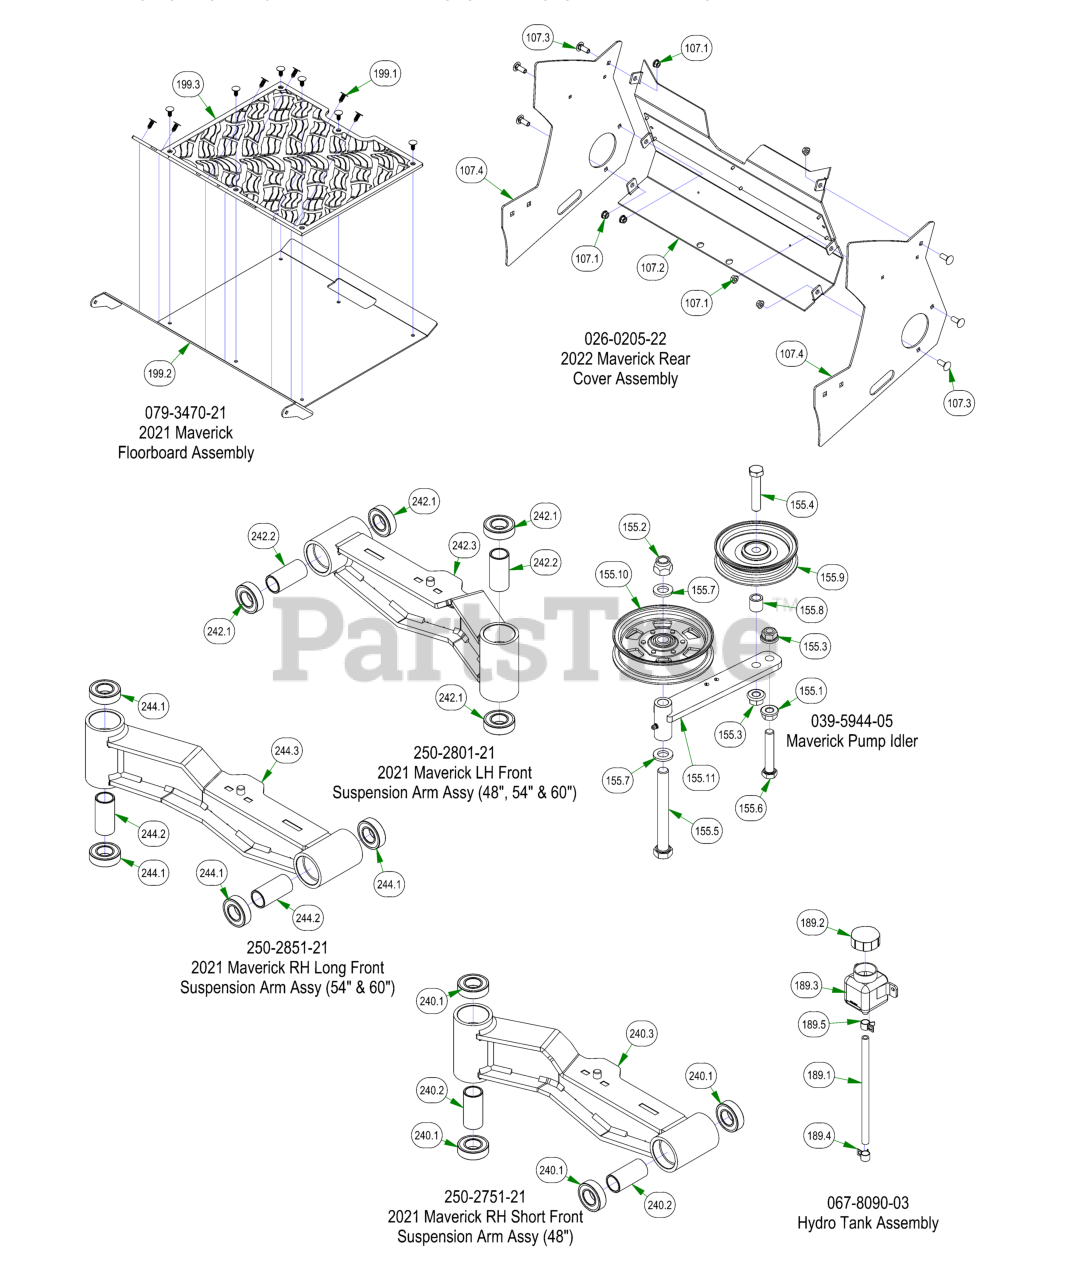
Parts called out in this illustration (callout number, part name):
59	5/16-18 X 1-1/4 CARRIAGE BOLT ZINC
107	2022 Maverick Rear Cover Assembly
107.1	5/16-18 NYLON INSERT FLANGE LOCKNUT ZINC
107.2	2021 Maverick Rear Cover Assembly
107.3	3/8-16 X 1 CARRIAGE BOLT (GR.5) ZINC
107.4	2022 Maverick Rear Cover Side Plate - Painted
108	2023 4" & 5" Stripping Kit Plate
155	Maverick Pump Idler
155.1	1/2-13 HEX SERRATED FLANGE NUT HARD/ZINC
155.2	5/8-11 NYLON INSERT LOCKNUT ZINC
155.3	1/2-13 NYLON INSERT FLANGE LOCKNUT ZINC
155.4	1/2-13 X 2-1/2 HEX CAP SCREW GR 5 ZINC
155.5	5/8-11 X 5-1/2 HEX CAP SCREW (GR.5) ZINC
155.6	1/2-13 X 2-3/4 HEX CAP SCREW (GR.5) ZINC
155.7	.635 ID X 1.120 OD X .140 THICK FLAT WASHER NYLON
155.8	.51 ID X .75 OD X .75 LGTH SOLID SPACER ZINC
155.9	4 3/4" Idler Pulley
155.10	5 3/4 Idler Pulley, 5/8 Bore
155.11	Deck Idler
189	Hydro Tank Assembly
189.1	ZT/Maverick Hydro Tank Hose
189.2	Hydraulic Tank Cap
189.3	350ml Expansion Tank
189.4	3/8" Hose Clamp
189.5	1/2 Hose Clamp
199	2021 Maverick Floorboard Assembly
199.1	Ratchet Fastener
199.2	2018 Maverick Floorboard
199.3	2021 Maverick Floor Mat W/ Reaper Tread
202	2023 ZT Stripping Kit Rubber
240	2021 Maverick RH Short Front Suspension Arm Assy (48")
240.1	1641 BEARING W/2 CONTACT RUBBER SEALS
240.2	2016 Front Bearing Spacer
240.3	2021 Maverick I-Beam Front Arm RH Short Weldment - Painted
242	2021 Maverick LH Front Suspension Arm Assy (48", 54" & 60")
242.1	1641 BEARING W/2 CONTACT RUBBER SEALS
242.2	2016 Front Bearing Spacer
242.3	2021 Maverick I-Beam Front Arm LH Weldment - Painted
244	2021 Maverick RH Long Front Suspension Arm Assy (54" & 60")
244.1	1641 BEARING W/2 CONTACT RUBBER SEALS
244.2	2016 Front Bearing Spacer
244.3	2021 Maverick I-Beam Front Arm RH Long Weldment - Painted
